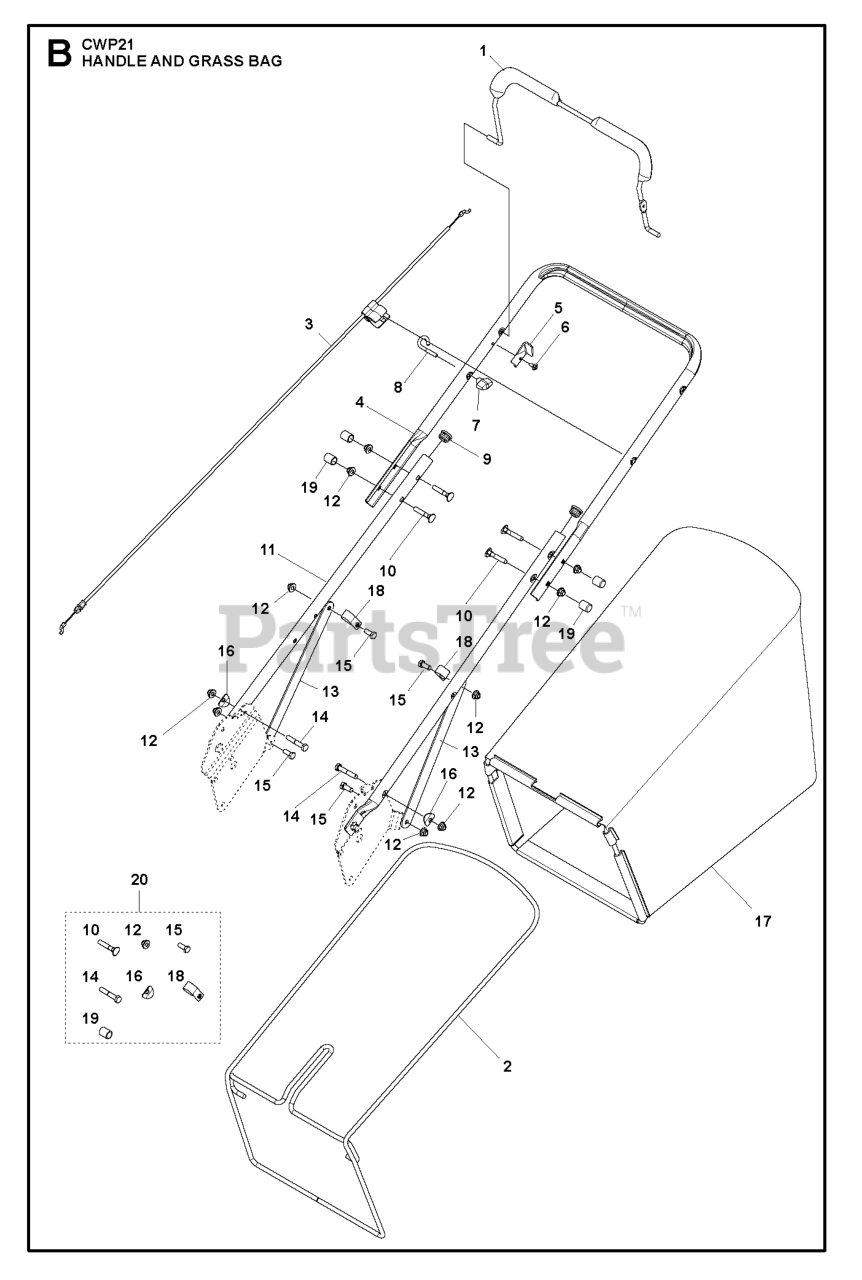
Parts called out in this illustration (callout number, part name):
1	BAIL.OM.STRT.MZR.BLACK.428
2	FRAME.GBAG.AWD.21.BLACK
3	CABLE.MZR.RGD.PLUS.STRT
4	HANDLEBAR UPPER, DST, EXT CRUS
5	BRACKET.UPSTOP.RT
6	SCREW
7	T-KNOB.NEW ROPE GUIDE
8	GUIDE.ROPE.BLK.ZINC.CHROM
9	PLUG.PLASTIC.7/8".14-20.GAUGE
10	BOLT, HANDLE 5/16-18X1.75
11	HANDLE LOWER, 21 COMMERCIAL BL
12	NUTNYLOK.FLRANGE.5/16-18
13	BRACE DIAGONAL HANDLE, 21 COMM
14	SCREW
15	BOLT HEXAGON HEAD 5/16-18"X3/4
16	WASHER CURVED 5/16"X1"X0.06" S
17	GBAG.C3610010.GENERIC
18	CLAMP LOOP, 7/8, 21 COMMERCIAL
19	COVER THREAD COVER BLACK
